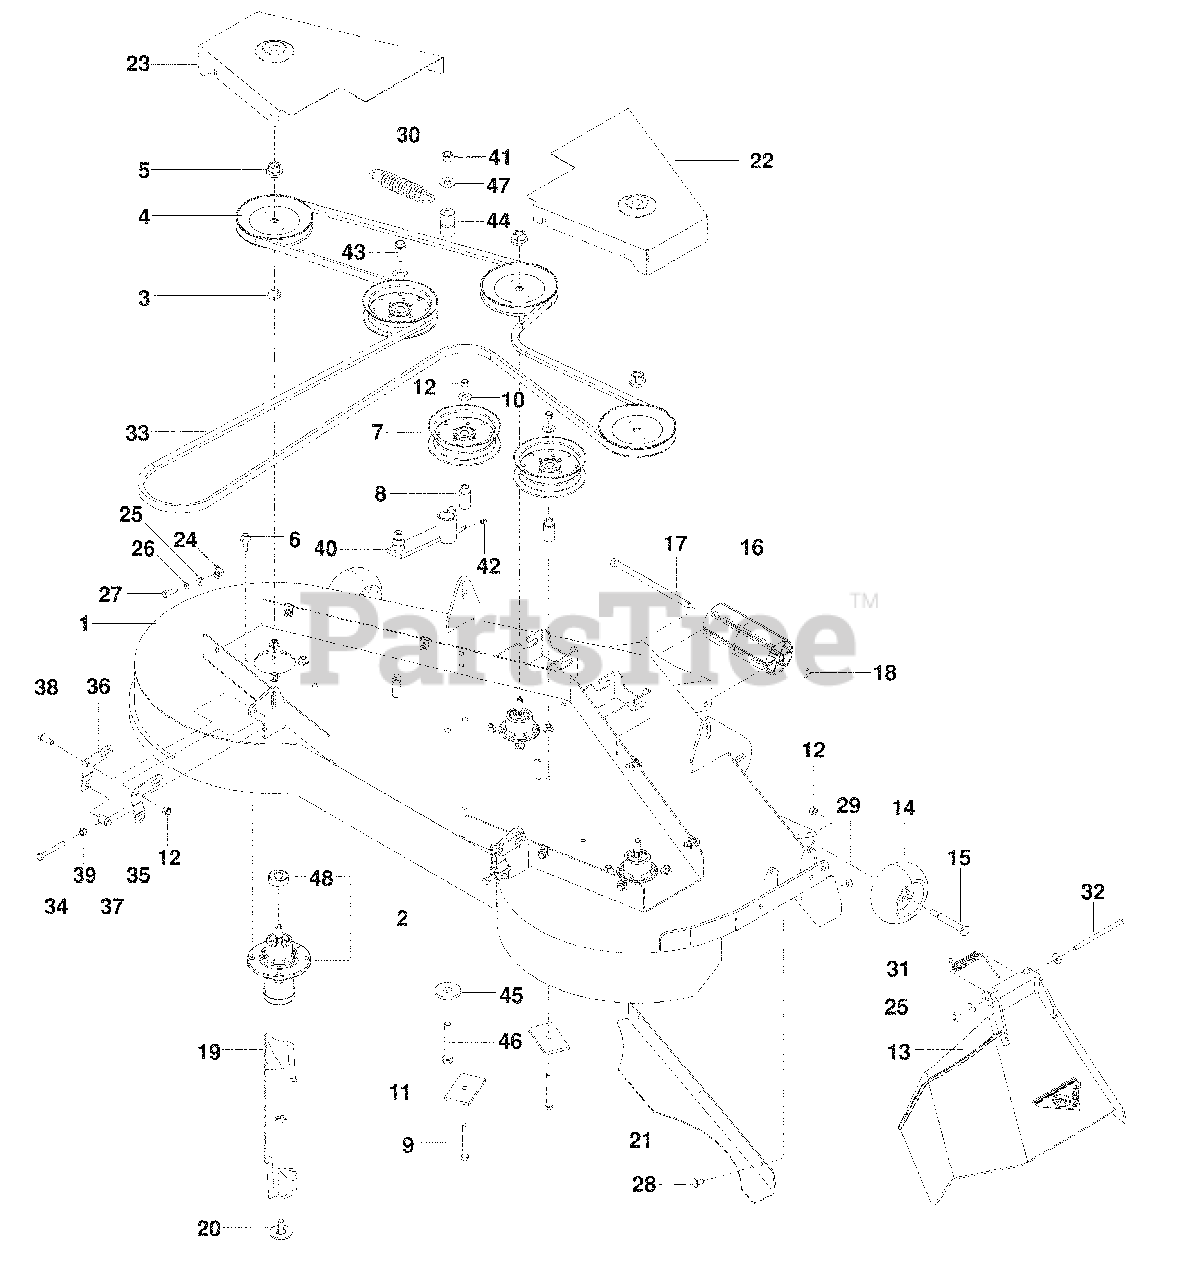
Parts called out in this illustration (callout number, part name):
1	DECK w/ SAFETY DECALS
2	HOUSING ASSEMBLY
3	WASHER-SPACER
5	NUT 9/16 TOP CENTER LOCK
6	SCREW, WASHER HEAD
7	PULLEY, IDLER
8	IDLER BUSHING
9	BOLT, HEX 3/8-16 x 3
10	WASHER 3/8 FLAT STD
11	PAD
12	NUT 3/8-16 HEX NYLOC
13	DISCHARGE CHUTE, 61"
14	WHEEL, GAUGE
15	BOLT, SHOULDER
16	ROLLER, NOSE, 48"
17	ROD, ROLLER, NOSE
18	PIN, COTTER 1/8 x ¾
19	BLADE, 21"
20	BOLT 7/16 BLADE
21	CONFINEMENT PLATE
22	BELT SHIELD, RH
23	BELT SHIELD, LH
24	RETAINER, U TYPE
25	WASHER 5/16 STD FLT
26	WASHER 5/16 SLW
27	BOLT, HEX 5/16-18 x 1
28	BOLT, RD HD 5/16-18 x 5/8
29	NUT 5/16-18 HEX NYLOC
31	SPRING, TORSION
32	PIN, CLEVIS 5/16
33	BELT, DECK
34	BOLT, HEX 5/16-18 x 2½ TPBLT
35	PITCH, ADJUST, RT
36	PITCH, ADJUST, LT
37	TRUNION, PITCH
38	BOLT, HEX 3/8-16 x 1
39	NUT 5/16-18 HEX
40	IDLER ARM WELDMT
41	NUT ½ HEX NYLOC
42	ZERK
43	BOLT, HEX 3/8-16 x 1 WHIZLK
44	PIVOT BUSHING
45	SUPPORT WASHER
46	BOLT, HEX ½-13 x 3¼
47	WASHER ½ STD FLT
48	BALL BEARING
